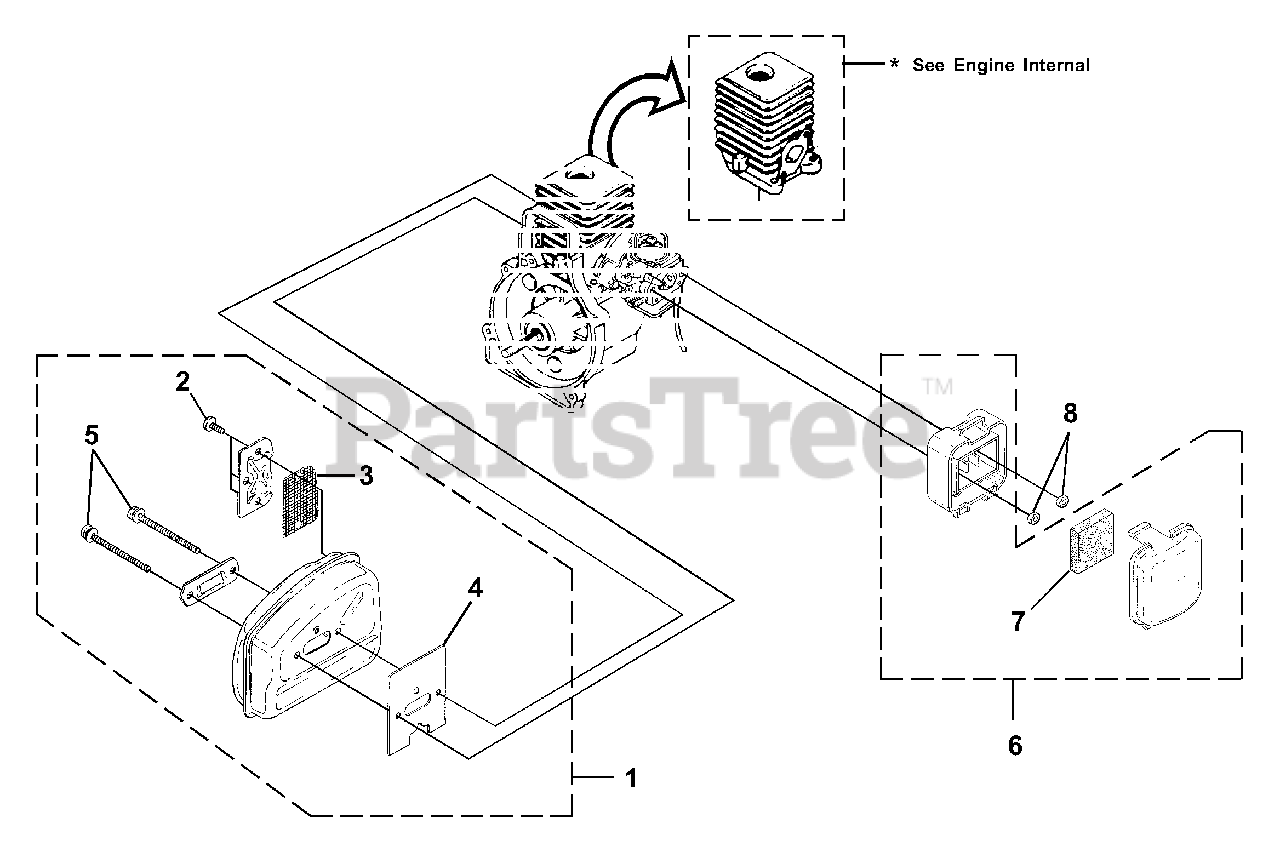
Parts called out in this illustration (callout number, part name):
1	MUFFLER ASSY.
2	SCREW, Taptite- (8-32 X 3/8")
3	SCREEN-Spark
4	GASKET-Muffler
5	SCREW, Truss Hd. - (10-24 X 2.188)
6	AIR FILTER KIT
7	FILTER-AIR
8	NUT-Hex (10-24)
